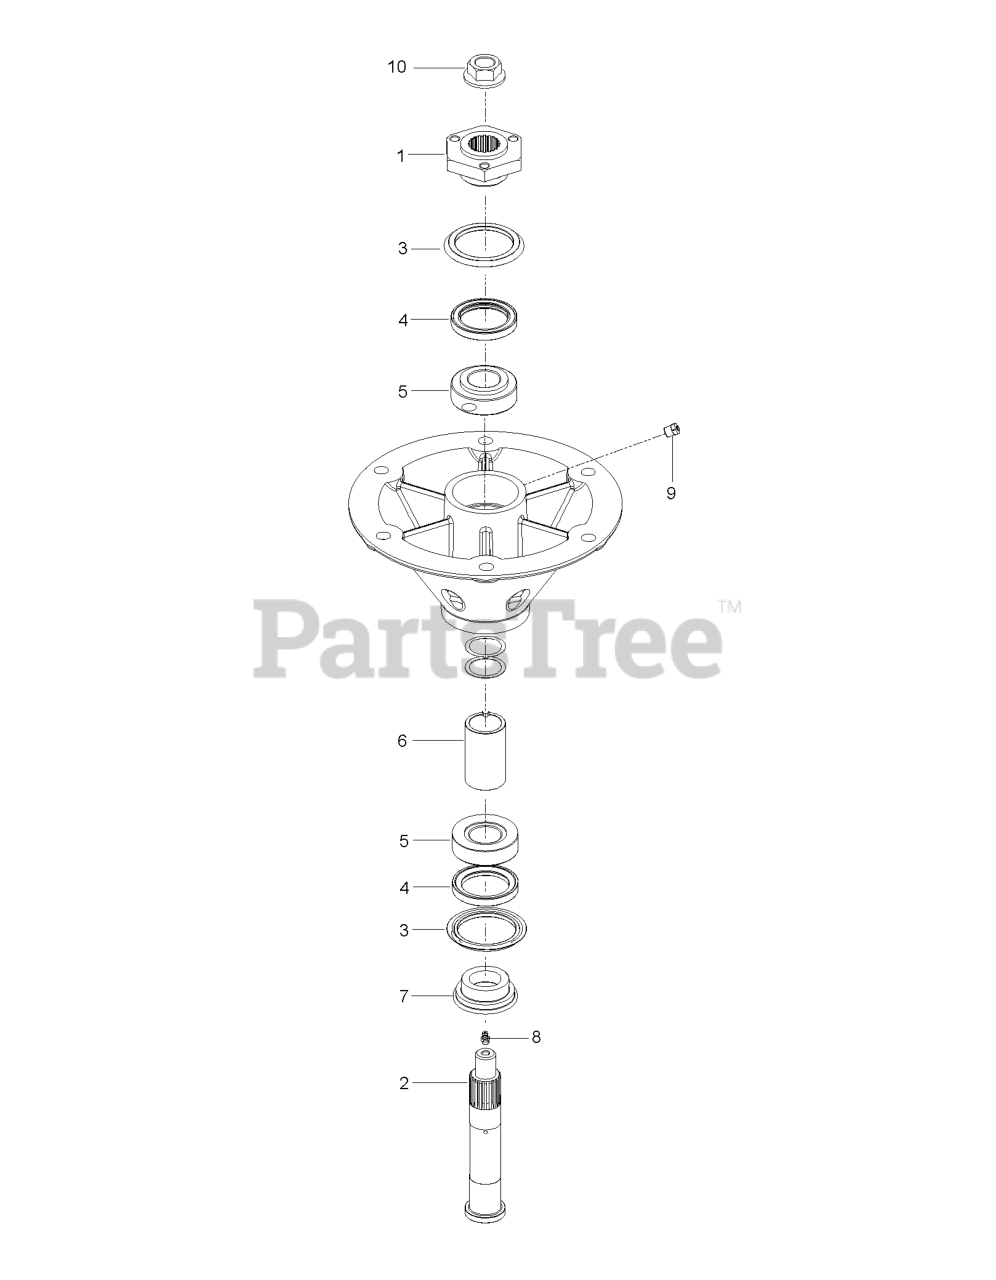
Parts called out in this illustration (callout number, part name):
3	SEAL V-RING 55MM
4	SEAL SHAFT
5	BEARING
8	ZERK
9	PLUG-VENTED
10	NUT FLANGE 3/4-16
